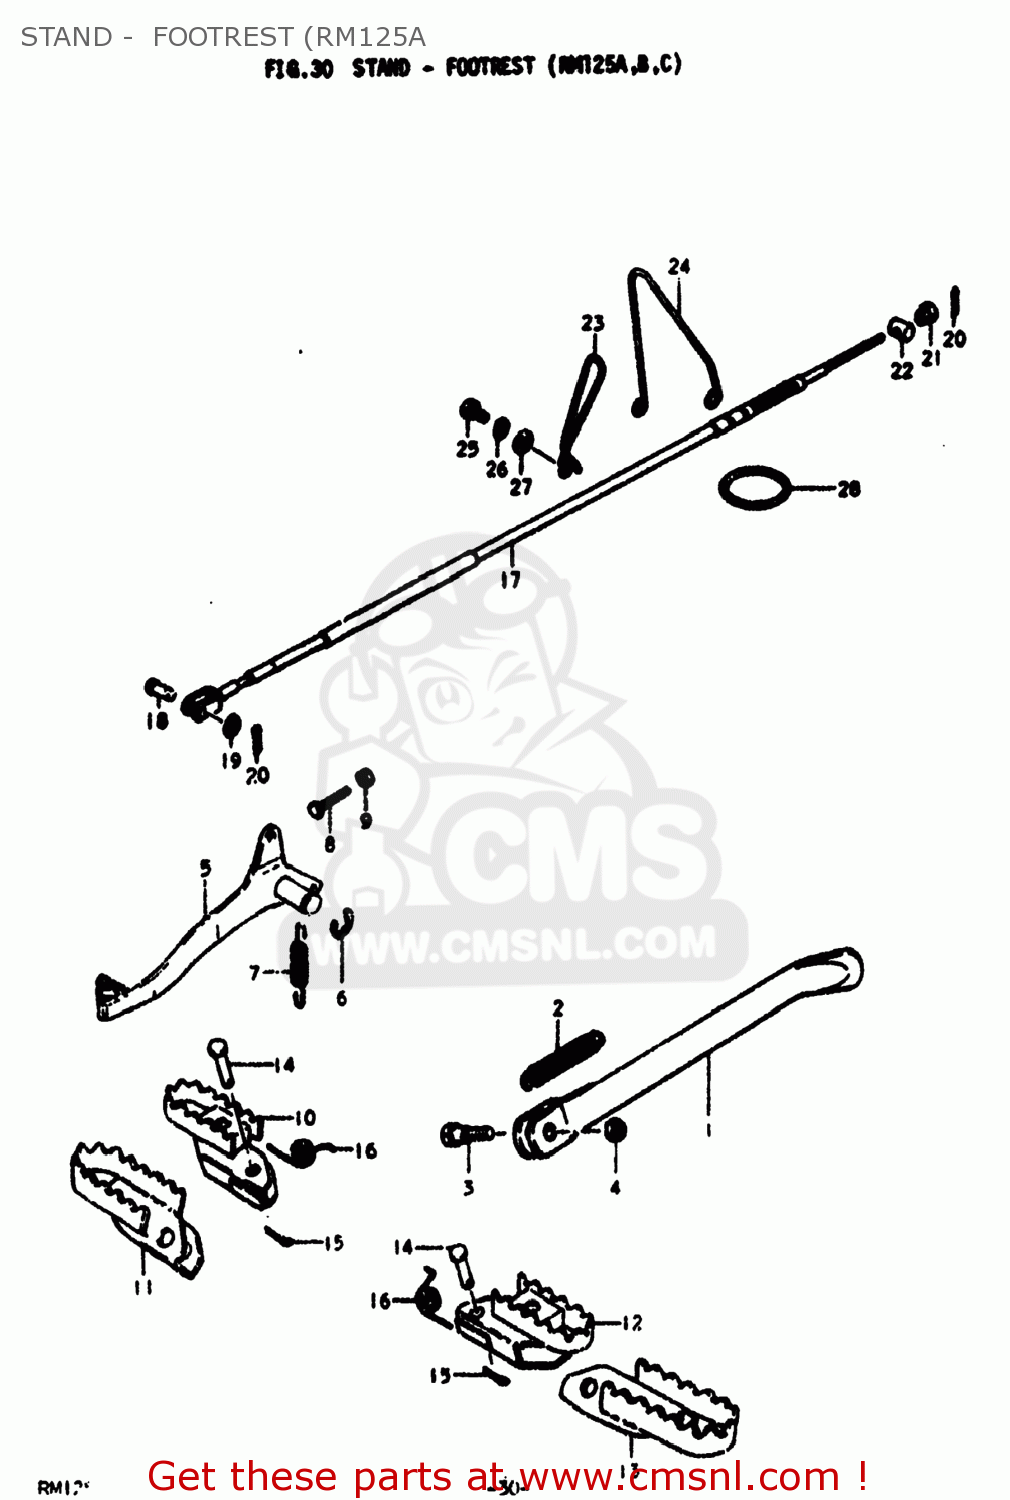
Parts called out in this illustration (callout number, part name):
1	STAND,SIDE
2	SPRING
3	BOLT(10X30)
4	NUT
5	PEDAL,BRAKE
6	E RING
7	SPRING
8	BOLT(6X25)
9	NUT
10	FOOTREST,FRONT
11	FOOTREST,FR,R
12	FOOTREST
13	FOOTREST,FR,L
14	PIN
15	PIN 20X20
16	SPRING
17	CABLE,RR BRAKE
18	PIN(L:17.5)
19	WASHER
20	PIN
21	NUT
22	PIN(11X18)
23	GUIDE,CABLE
24	GUIDE,CABLE
25	BOLT
26	LOCK WASHER
27	WASHER
28	O RING,RR BRAKE CABLE
